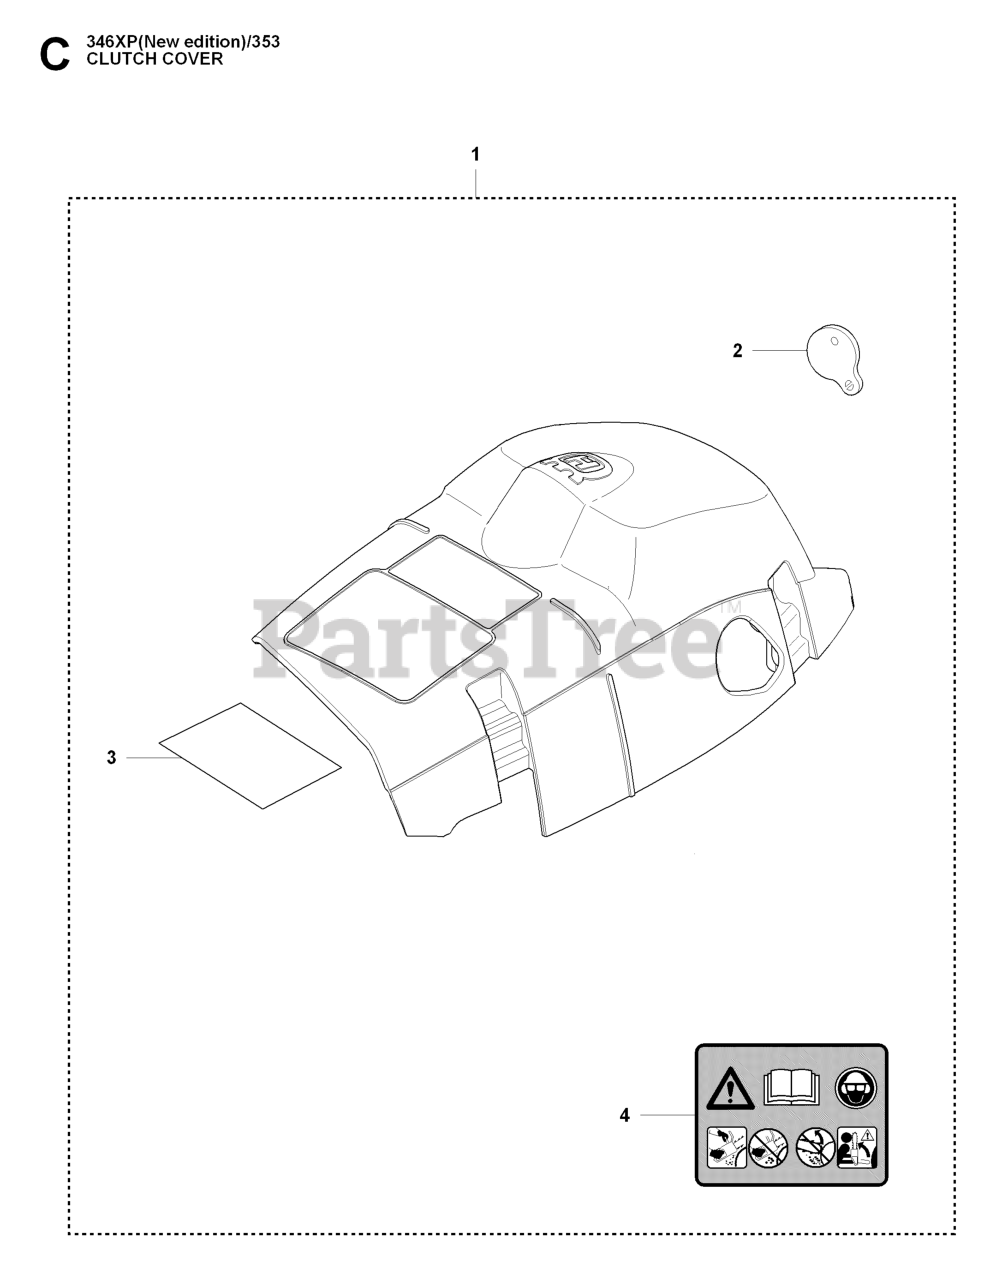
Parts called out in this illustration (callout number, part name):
1	CYLINDER COVER ASSY
2	COVER
3	INSULATING FOIL/CYLINDER COVER
